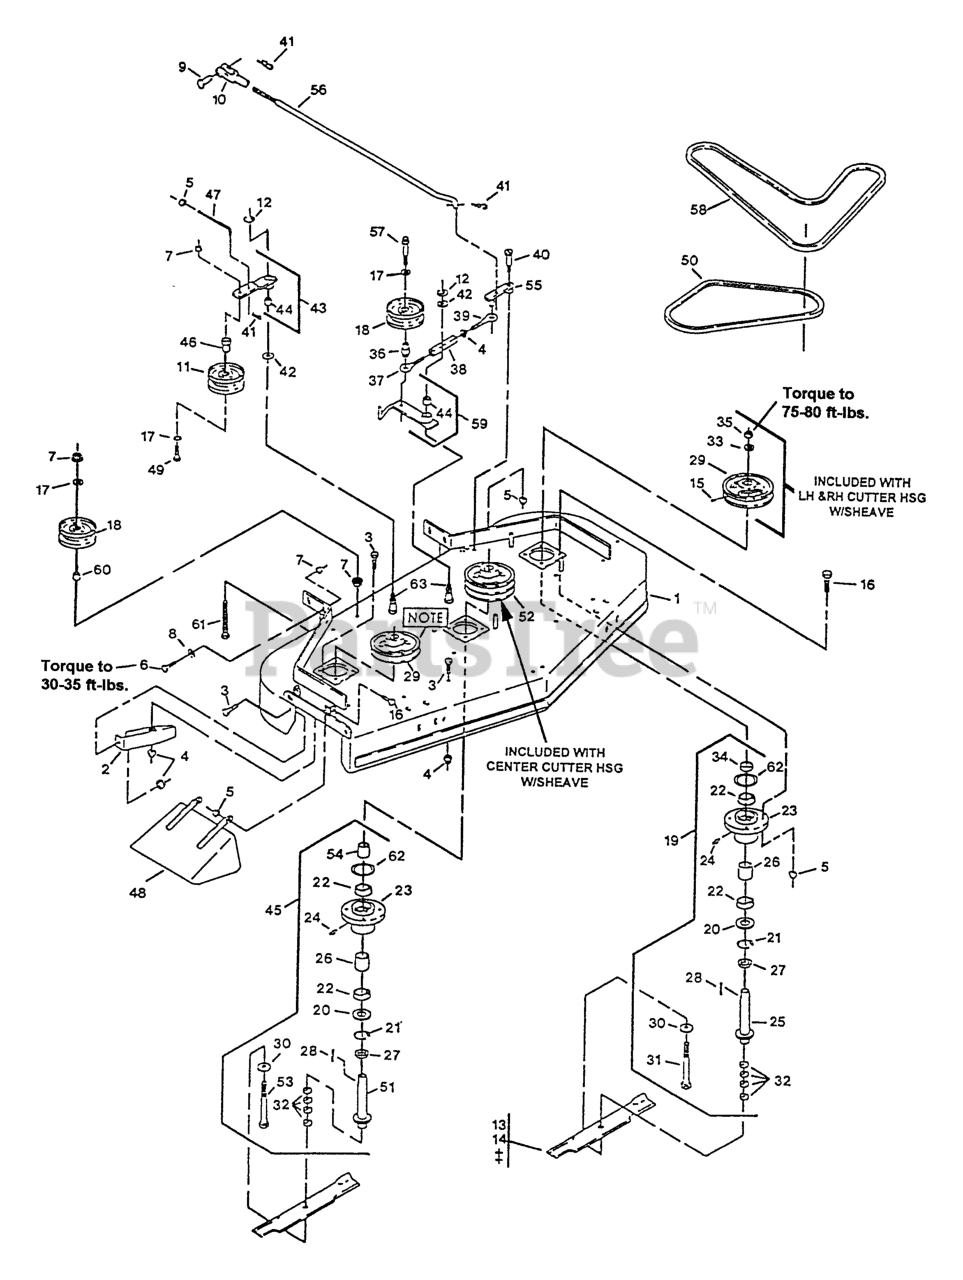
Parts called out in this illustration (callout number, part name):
2	BAFFLE-DOGLEG
9	PIN-CLEVIS
10	YOKE-ADJUSTABLE
11	IDLER,PULLEY
15	SCREW-SET
19	ASM,HOUSING CUTTER
20	SEAL,DUST
21	RING,SNAP WLDS N5000-244
22	BEARING,HD SPINDLE
23	HOUSING,CUTTER
26	SPACER,BRG/BRG
27	SPACER,BEARING &SPINDLE
30	WASHER-SPRING
31	SCREW-CAP, HH
33	WASHER-RETAINER, SHEAVE
36	BUSHING-ENGAGEMENT
37	EYEBOLT-THREAD, LH
38	BODY-TURNBUCKLE
39	EYEBOLT-THREAD, RH
40	BOLT,SHLDR KSKH
41	PIN-COTTER
42	WASHER-SPINDLE
43	ARM WLDMNT W/BUSHING
44	BEARING,POWDERED METAL
46	BUSHING-IDLER
47	LINKAGE
48	Chute
50	BELT,FRONT DECK
53	SCRW,CAP HH 5/8-18X8.5
54	SPACER,BEARING/SHEAVE
58	BELT,BLADE DRIVE 48
60	BUSHING,IDLER
61	BOLT,TAP HH3/8-16X2-1/4
